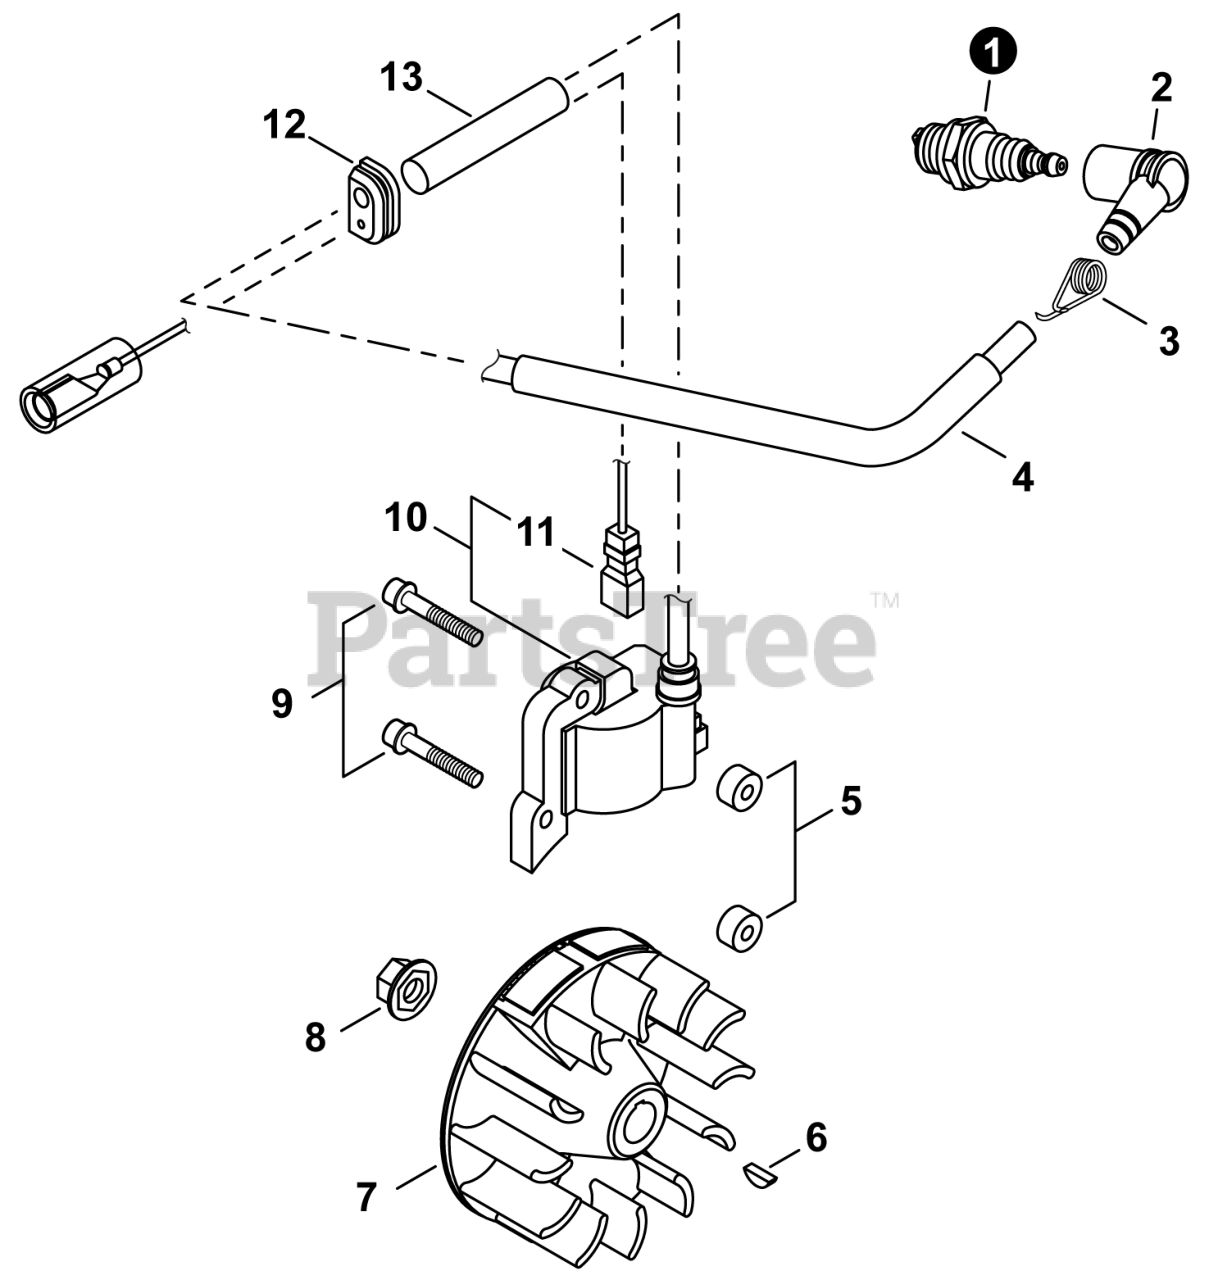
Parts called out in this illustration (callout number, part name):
1	SPARK PLUG - BMR6A
2	CAP, SPARK PLUG
3	TERMINAL, SPARK PLUG
4	TUBE, INSULATOR
5	INSULATOR 4.2×11×6
6	KEY, WOODRUFF 3×10
7	FLYWHEEL
9	BOLT 4×26
10	COIL ASSY, IGNITION
12	GROMMET
13	TUBE, IGNITION COIL
